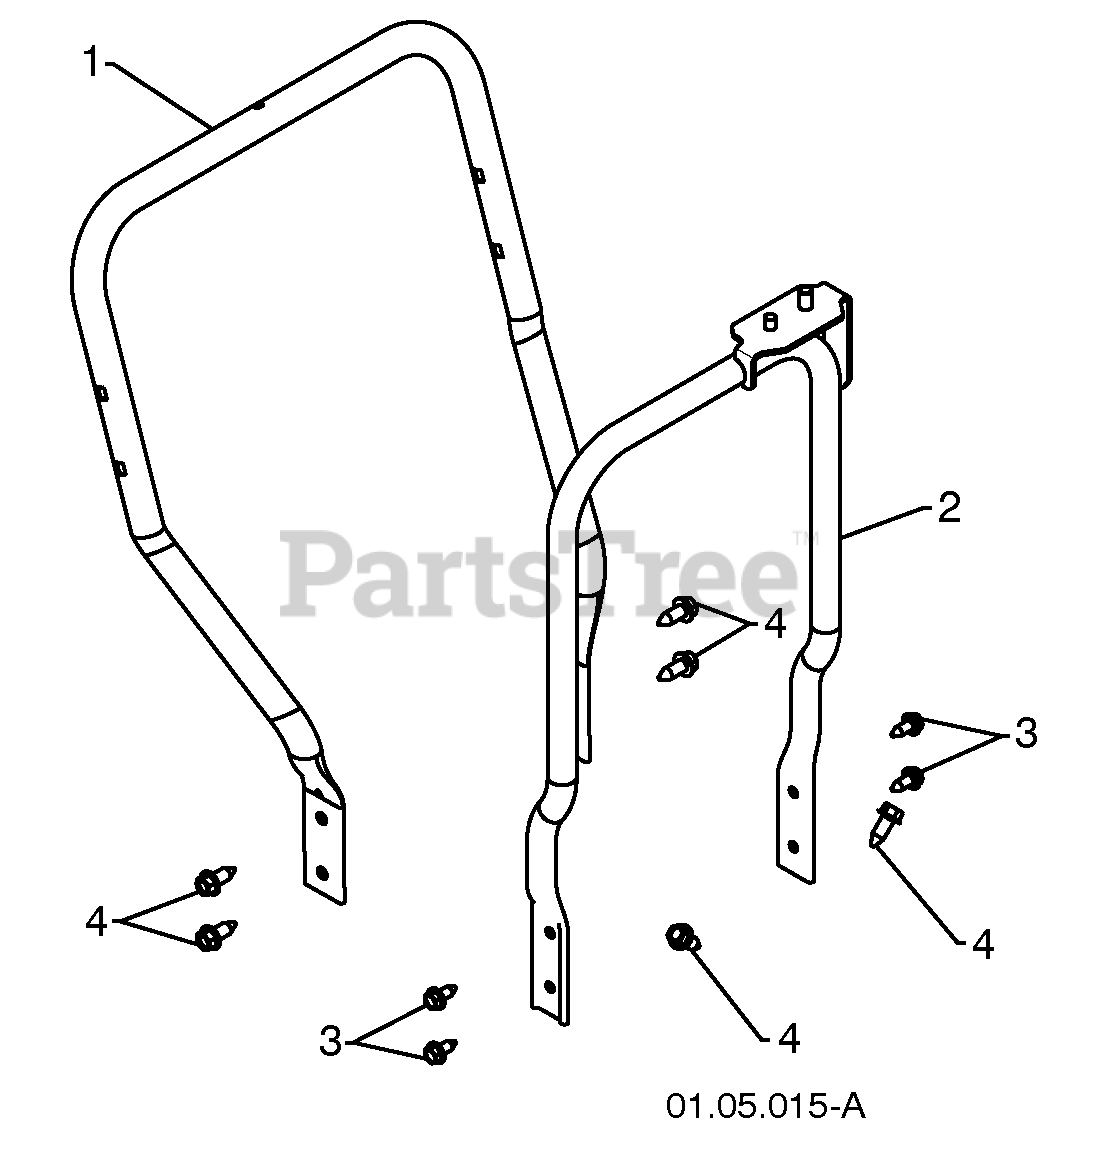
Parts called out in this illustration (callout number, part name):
1	Lower Handle
2	Pivot Support
3	Bolt 5/16-18 X .750
4	Screw 3/8-16 X 1.00
